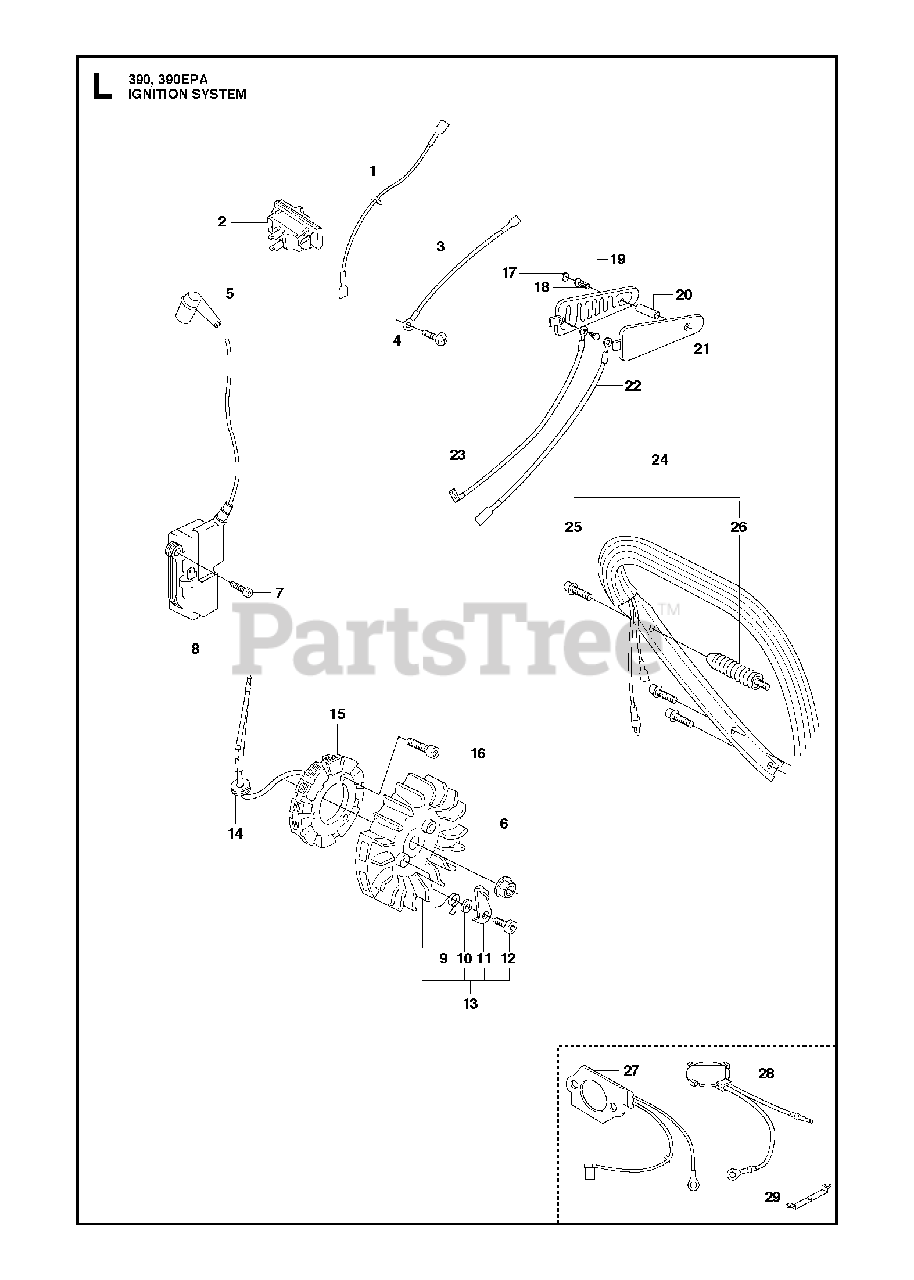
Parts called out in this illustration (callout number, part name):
2	START/STOP SWITCH
2	SWITCH (G)
5	SPARK PLUG CONN. KIT
6	NUT W/ WASHER
8	IGNITION MODULE
9	SPRING
10	WASHER
11	PAWL
12	SCREW M5X14
13	FLYWHEEL
14	GROMMET
15	GENERATOR
16	SCREW MC6S 4X12
17	WASHER
18	SCREW 3X10
19	SCREW
20	SPACER
21	HANDLE
22	CABLE
23	CABLE
24	FRONT HANDLE HEATED
25	SCREW
26	VIBRATION ABSORBER
27	FOIL ELEMENT
28	THERMOSTAT
